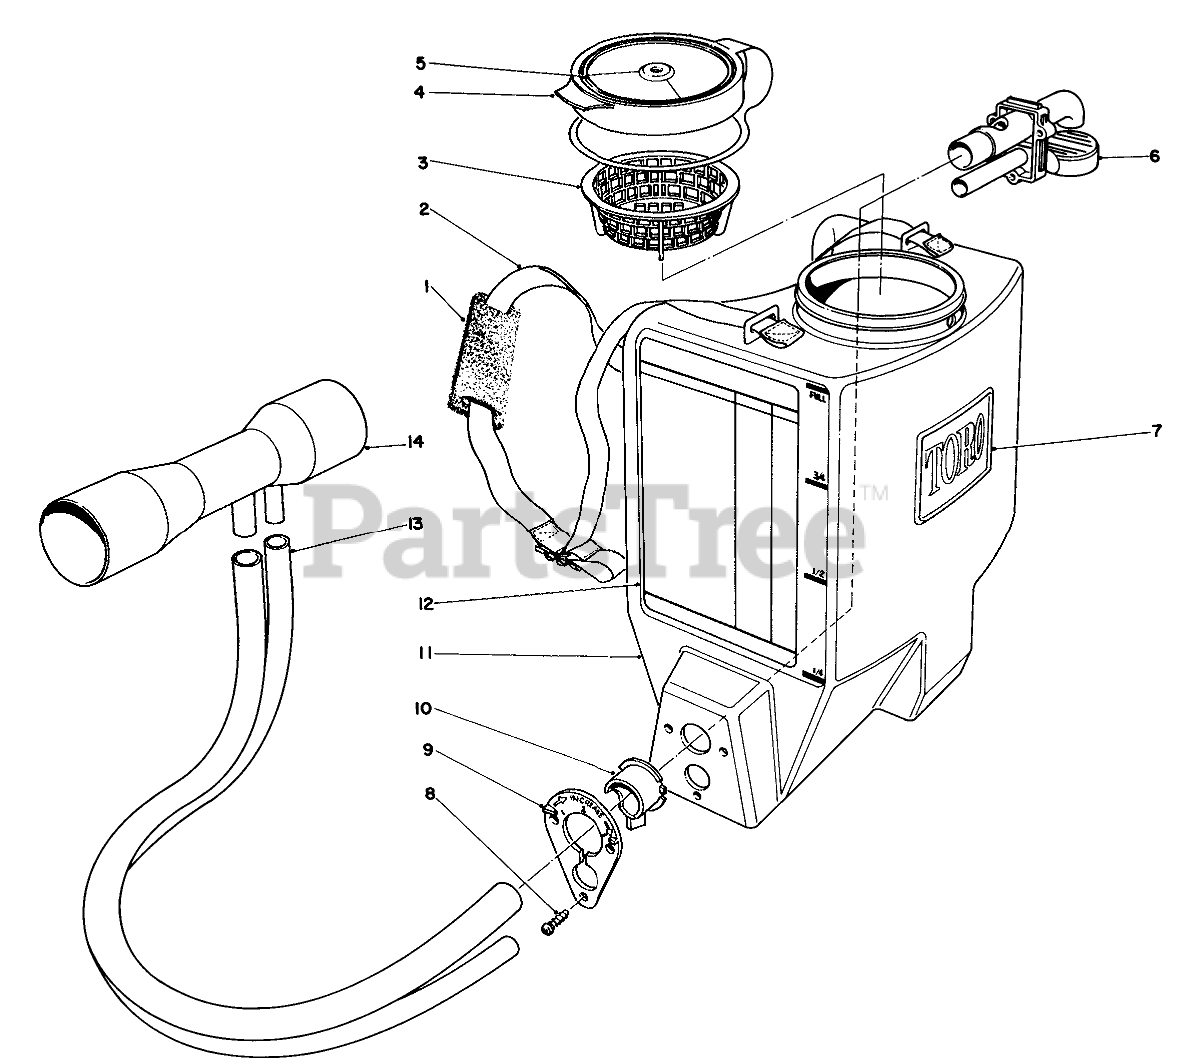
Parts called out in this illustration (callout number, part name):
1	SHOULDER PAD
2	Shoulder Strap
3	Strainer
5	CAUTION LABEL
6	PICKUP ASM MIXER
7	Decal-Toro
8	Screw
9	Bezel
10	Valve Delivery
11	CONTAINER
12	Label-Application
13	Tubing 2 Cell
14	ENTURI
